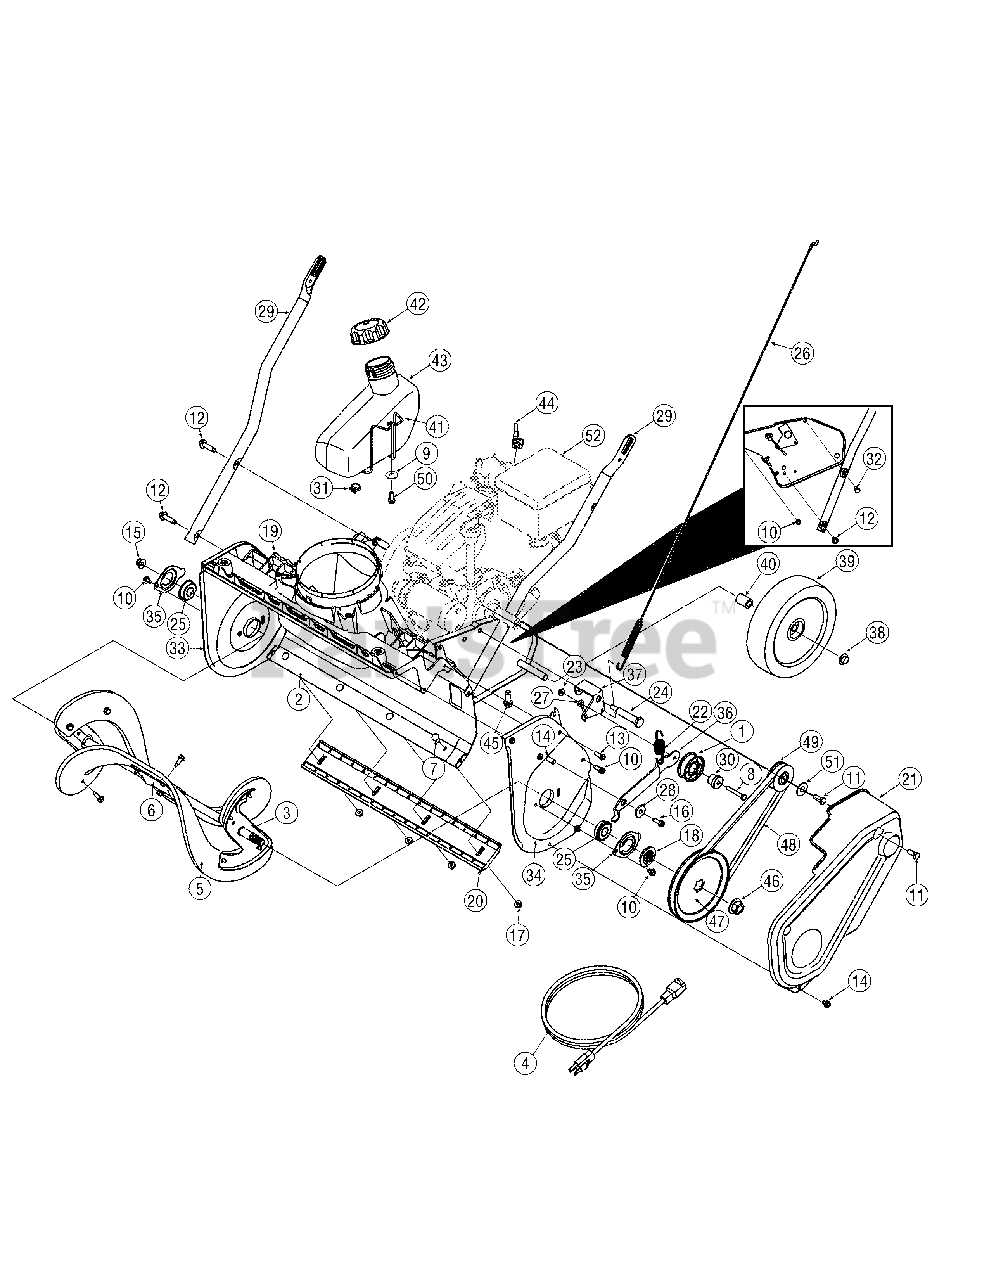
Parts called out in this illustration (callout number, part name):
1	Idler Pulley Assembly
2	Frame
3	Auger Paddle Assembly Complete
3	Auger Axle Assembly
4	3-Prong Extension Cord
5	Auger Paddle Replacement Kit
6	Center Auger Bracket
7	Carriage Screw, 1/4-20 x .62
8	Hex Washer Screw, 1/4-20 x 1.500
9	Flat Washer, .265 x 1.000 x .030
10	Hex Washer Screw, 1/4-20 x .625
11	Hex Lock Screw, 5/16-24 x .750
12	Hex Washer Screw, 5/16-18 x 1.250
13	Hex Washer Screw, 1/4-15 x .750
14	Hex Washer Screw, 1/4-20 x .500
15	Flange Lock Nut, 3/8-16
16	Hex Washer Screw, 5/16-18 x .750
17	Flange Lock Nut, 1/4-20
18	Pulley Hub
19	Chute Adapter
20	Shave Plate
21	Belt Cover
22	Extension Spring, .70 x 3.035
23	Push Nut, .25 x .50
24	Shoulder Bolt, 5/16-24 x .496 x 2.18
25	Ball Bearing
26	Clutch Cable
27	Drive Cable Wire Support
28	Shoulder Spacer
29	Lower Handle
30	Shoulder Spacer, .260 x .785 x .538
31	Hose Clamp, .490
32	Hex Screw, 5/16-24 x 1.25
33	RH Auger Plate
34	LH Auger Plate
35	Bearing Cup
36	Idler Bracket
37	Cable Idler Bracket
38	Push Cap, 1/2
39	Wheel, 8 x 1.7
40	Sleeve Spacer, .525 x .78 x 1.00
41	Gas Tank Wire Support
42	Fuel Cap
43	Fuel Tank, 2 qt.
44	Choke Extension Lever
45	Hex Washer Screw, 3/8-16 x 1.000
46	Flange Nut, 9/16-20
47	Pulley, 1/2 x 6.00
48	Belt, .500 x 35.06
49	Pulley Half, .625 x 2.25
50	Tri-Plask Screw, 1/4-10 x .625
51	Flat Washer, .330 x 1.250 x .120
52	Replacement Engine
